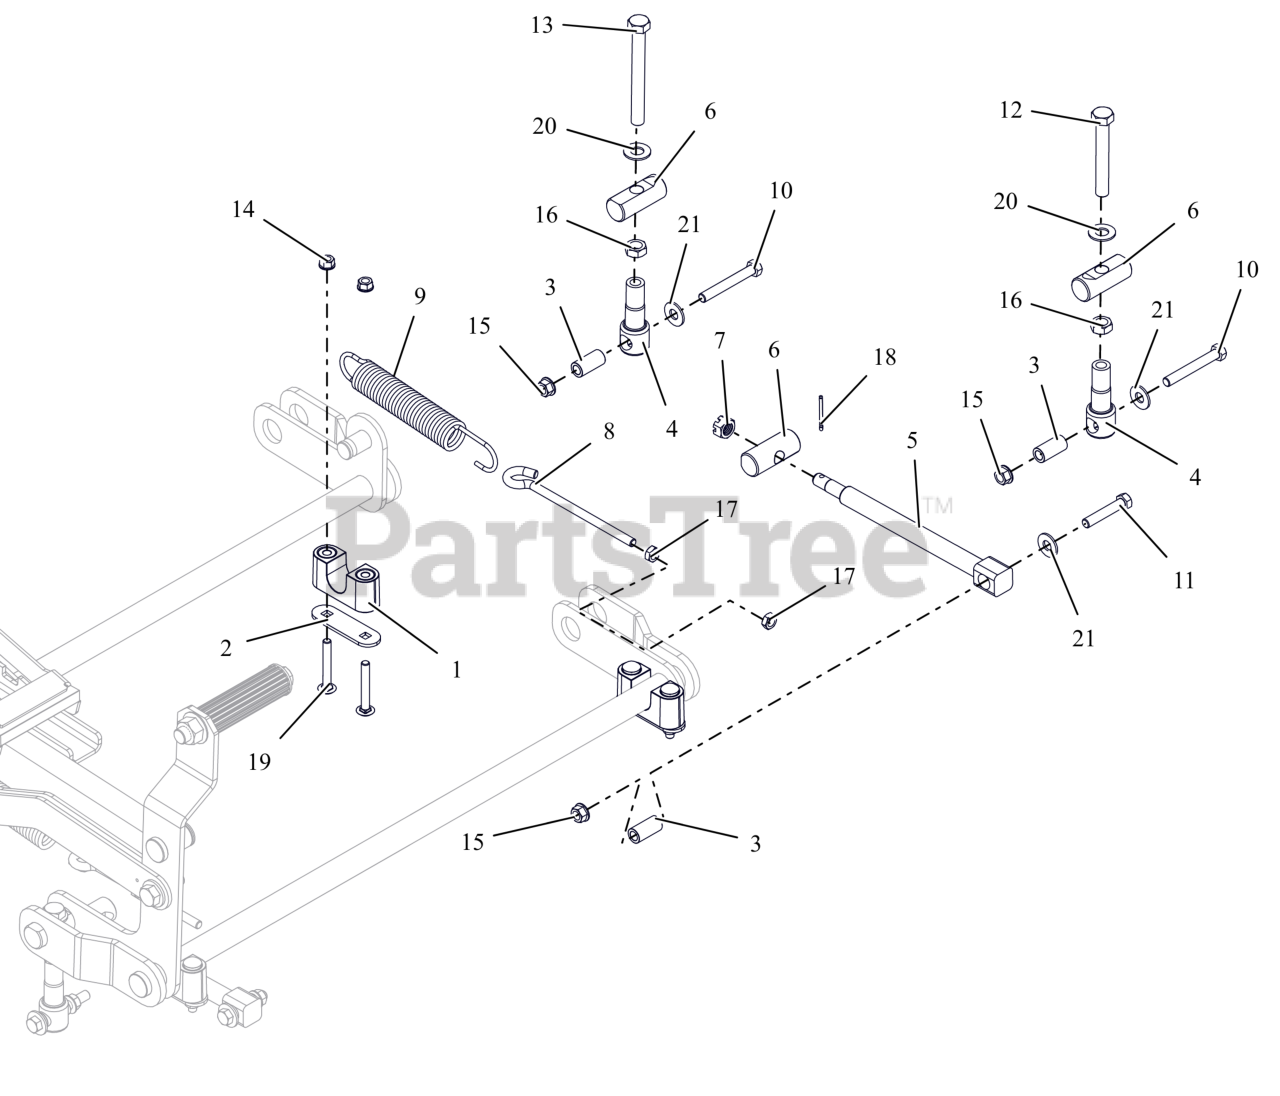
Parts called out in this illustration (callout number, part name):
1	ASM-BUSHING, DECK LIFT
2	PLATE, BEARING SUPPORT
3	SPACER, DECK LEVELING
4	LINK, DECK LIFT FORMED
5	DRAG,LINK-HD
6	PIN, DECK LIFT
7	NUT-SL .50-13
8	BOLT,.38-16 X 5.25-.62 DIA EYE
9	SG-TENS .162X1.25X8.25 WLD 25
10	BLT, HEX .38-16X2.75 G8 ZCC
11	BLT,HEX .38-16X2.00 G5 ZCC
12	BLT, HEX .50-13X3.50F G5 ZCC
13	BLT, HEX .50-13X4.50F G8 ZCC
14	NUT,LK-CTR-FLG .31-18 GF ZCC
15	NUT-LK-TOP-FLG .38-16 ZC120
16	NUT-JAM .500-13 G2 ZCC
17	NUT-JAM .375-16 G2 ZCC
18	PIN,CTR.12X1.25EXTPRSQCT ZC120
19	BLT, RHSSN.31-18X2.25 G5 ZCC
20	WSHR, FLT .557X1.040X.102 ZCC
21	WSHR,FLT .438X1.00X.083 ZCC
